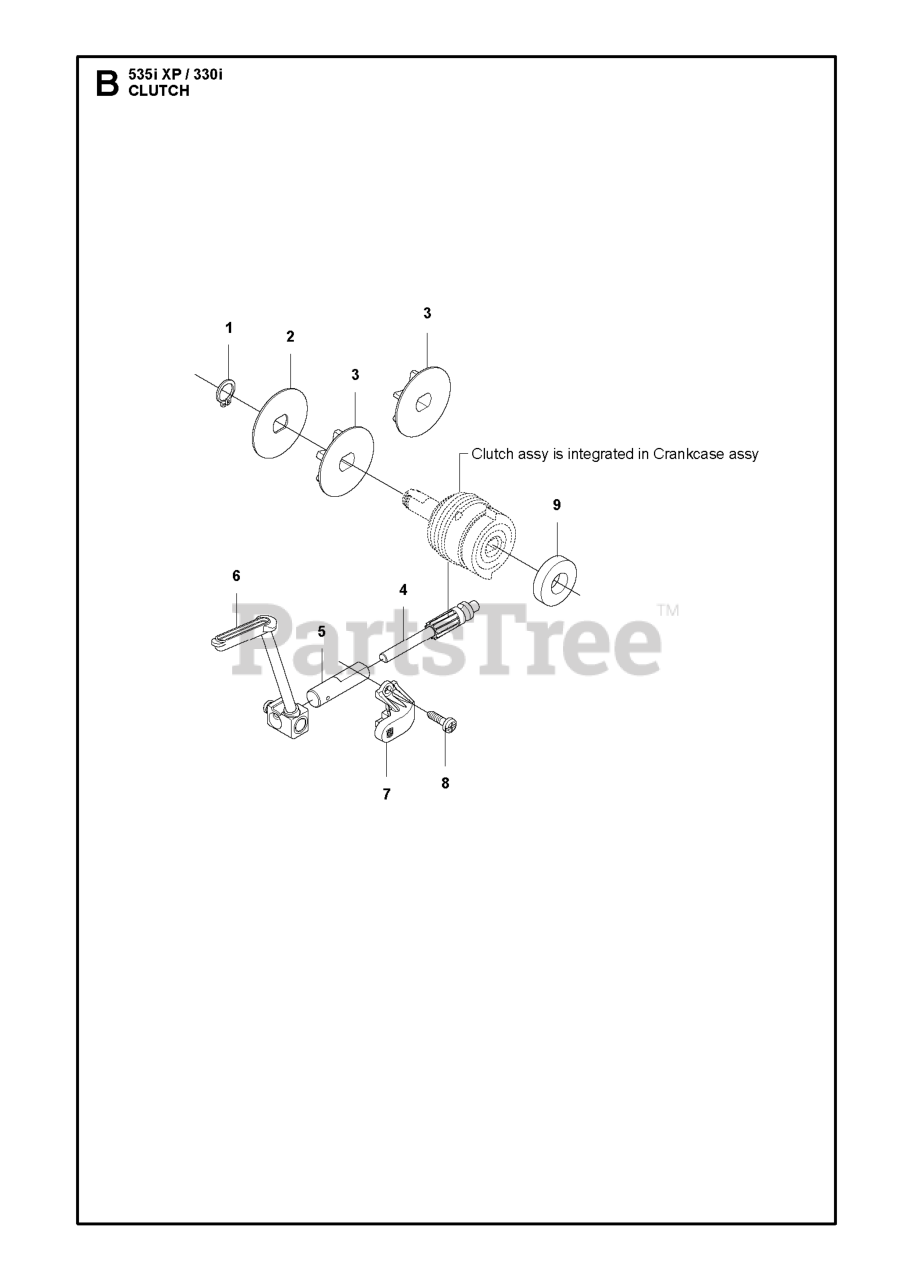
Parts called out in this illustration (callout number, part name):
1	RETAINING RING SGA 10
3	SPUR SPROCKET
3	SPUR SPROCKET 1/4" 8T
4	PISTON PUMP
5	PUMP CYLINDER
9	DISTANCE
